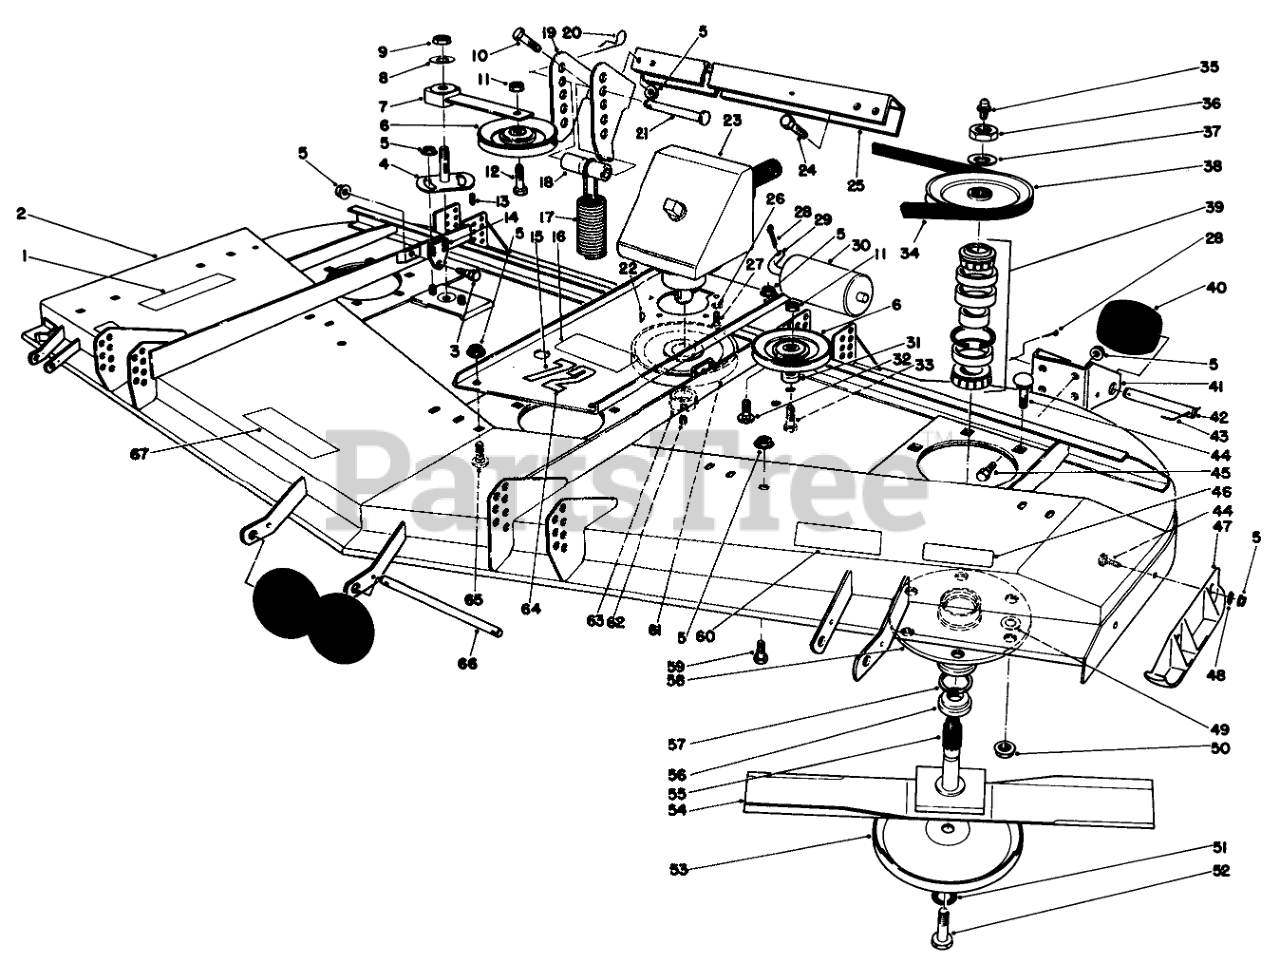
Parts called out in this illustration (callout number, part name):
1	DECAL-CAUTION, DEFLECTOR
2	Housing
3	BOLT-SHOULDER
4	PLATE-IDLER
5	NUT-HHF, WHIZ
6	Pulley
7	IDLER ARM ASM
8	WASHER-FLAT
9	NUT-LOCK, NI
10	SCREW-HH
11	NUT-HEX
12	SCREW-HH
13	KEY-SQUARE
14	SPRING END R
15	GEARBOX BASE R
16	Decal-Caution
17	Spring-Extension
18	SPACER
19	SPRING BRACKET R
20	PIN-HAIR
21	PIN-CLEVIS
22	KEY-WOODRUFF
23	GEAR BOX ASM
24	SCREW-HH
25	Adapter-Spring Bracket
26	WASHER-LOCK
27	SCREW-HSH
28	PIN-COTTER
29	SHAFT-ROLLER, REAR
30	ROLLER-DECK
31	SPACER
32	SCREW-CARR
33	SCREW-HH
34	V-BELT (72)
35	FITTING-GREASE
36	NUT-HEX
37	WASHER
38	PULLEY & HUB ASM, WELDED
39	BEARING ASM
40	ROLLER
41	Bracket-Roller
42	SHAFT-ROLLER
43	PIN-SPECIAL
44	SCREW-CARR
45	SCREW-HH
46	DECAL-CAUTION, BLADE
47	Skid
48	LOCKWASHER-PYRAMID
49	WASHER-FLAT
50	NUT-HF
51	WASHER-LOCK
52	SCREW-BLADE
53	Cup-Scalp
54	Blade
55	SHAFT
56	SPACER
57	SEAL-OIL
58	HOUSING-SPINDLE
59	SCREW-HH
60	REAR WEIGHT DECAL
61	PULLEY WA BO
62	SCREW-SET, HSH
63	BUSHING-LOCK, TAPER
64	DECAL
65	SCREW-CARR
66	SHAFT-ROLLER
67	CAUTION DECAL
